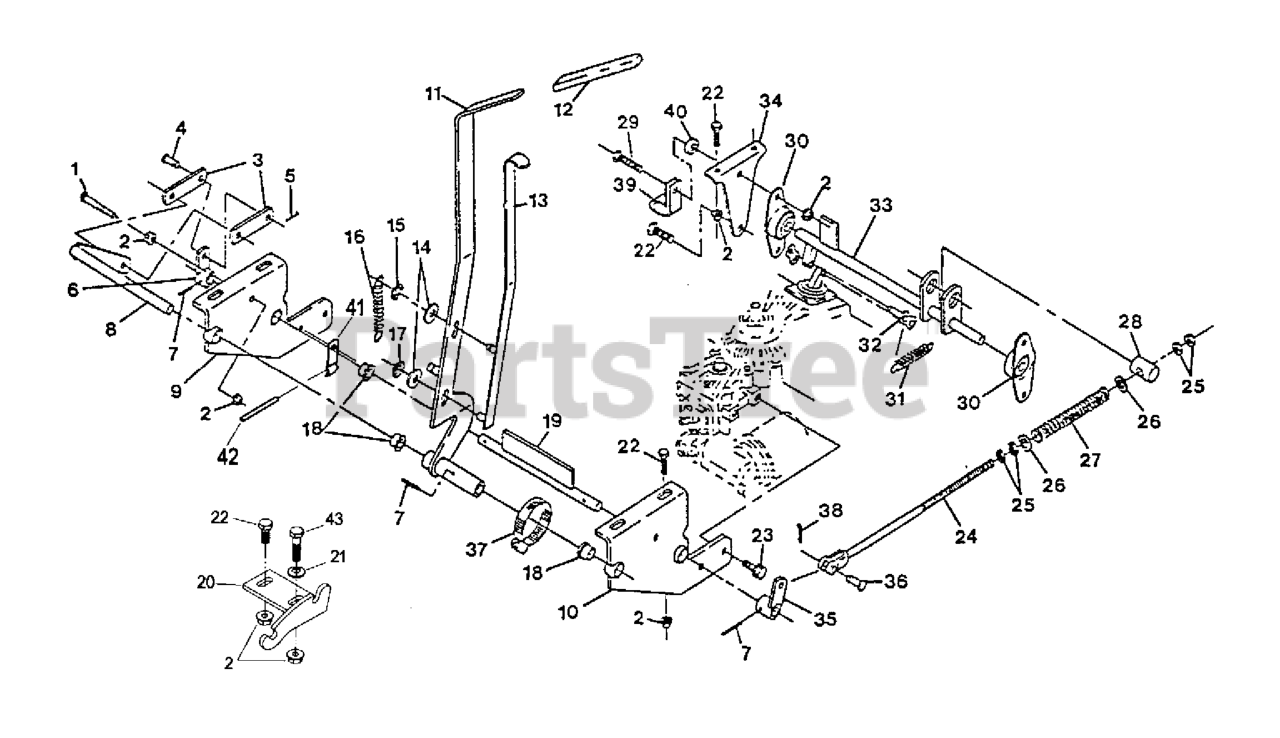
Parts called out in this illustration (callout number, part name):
1	SCREW-HH
3	LINK,BRAKE PLTD
4	PIN-CLEVIS
5	PIN-COTTER
6	WLD,CONTROL ARM
8	PIVOT - BRKT/LEVER
10	WLD,TRANSAXLE SUPPORT RH
12	GRIP-LEVER
14	WASHER-PLAIN
15	RING-RETAINING, EXT
16	SPRING,BRAKE HANDLE
17	NUT,PUSH
18	BEARING-CONTROL
19	WLD,BUTTERFLY
20	WLD,BRAKE QUADRANT
21	WASHER-SPRING
22	SCREW-HH
23	SCREW-HHF
24	LINKAGE,BRAKE
25	NUT-HJ
26	WASHER-FLAT
27	SPRING,COMPRESSION
28	PIN,TRUNION
29	SCREW-HH
30	FLANGE MTG, SIDE
32	LINK,CONNECTING
33	WLD,BRAKE JACKSHAFT
36	PIN-CLEVIS
37	CLAMP-HOSE
38	PIN-COTTER
40	SPACER,CLUTCH ANCHOR
41	SPRING,DUMP VALVE
42	ROLLPIN PLTD
43	SCREW-HH
